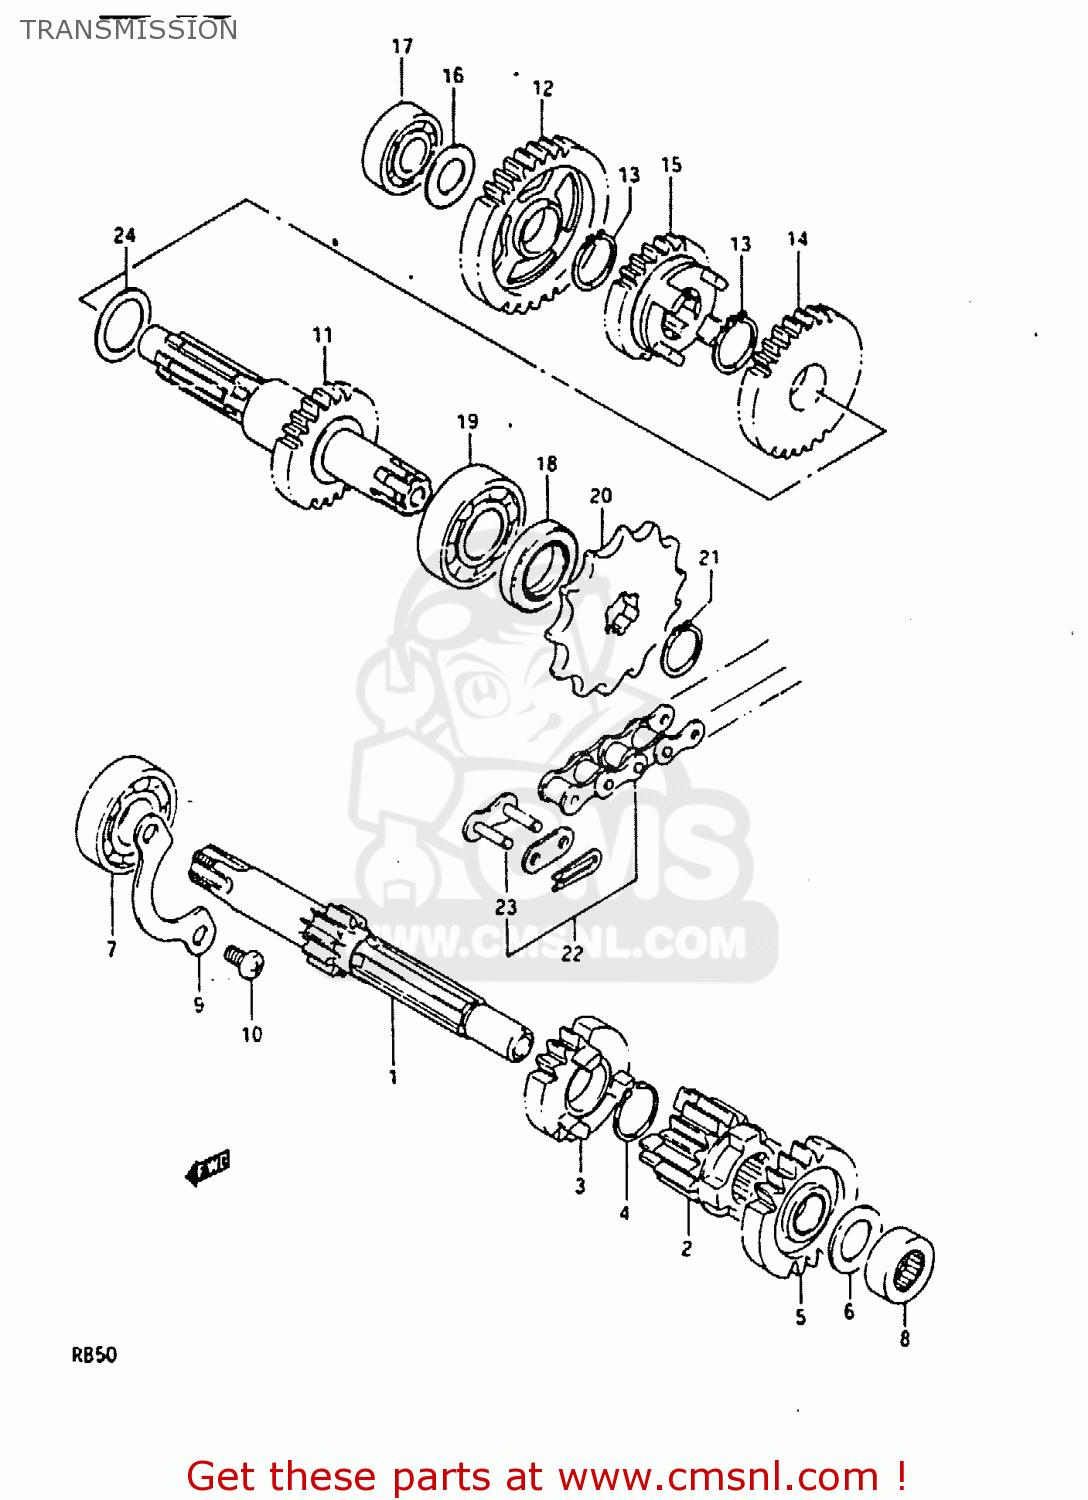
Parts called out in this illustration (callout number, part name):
1	SHAFT,COUNTER
3	GEAR,THIRD DRIVE
4	CIRCLIP
5	GEAR,FOURTH DRIVE (NT:21)
6	WASHER
7	BEARING
8	BEARING(12X19X12)
9	RETAINER,BEARING
10	SCREW
12	GEAR,1ST DRIVEN(NT:34)
13	CIRCLIP
14	GEAR,2ND DRIVEN(NT:29)
15	GEAR,THIRD DRIVEN
16	WASHER
17	BEARING
18	OIL SEAL
19	BEARING(17X40X12)
20	SPROCKET,ENGINE(NT:14)
21	CIRCLIP,16MM
22	CHAIN ASSEMBLY,DRIVE
23	JOINT
24	WASHER
